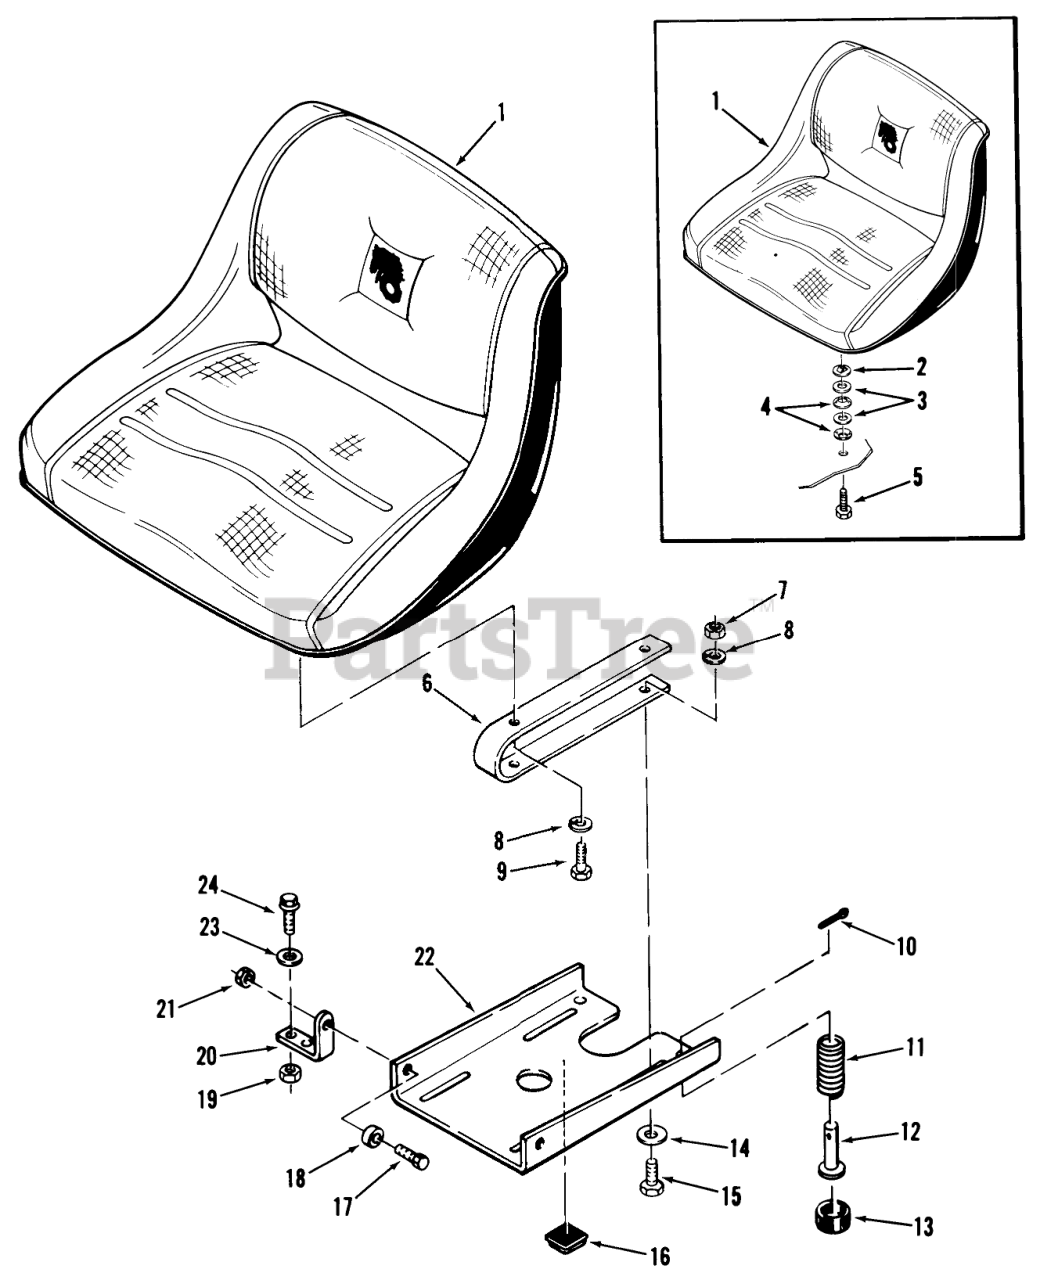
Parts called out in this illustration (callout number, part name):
1	Seat
2	NUT-PUSH
3	Washer 5/16
4	WASHER-SPRING
5	SPECIAL BOLT
6	Spring
7	Nut
8	Lockwasher
9	Bolt
10	Cotter Pin
11	SPRING
14	WASHER 5/16 SAE
15	HHCS
16	BUMPER
17	HHCS
18	BUSHING
19	Nut
20	BRACKET-PIVOT
21	Nut
22	Plate-Seat Pivot
23	WASHER 5/16 SAE
24	Bolt
